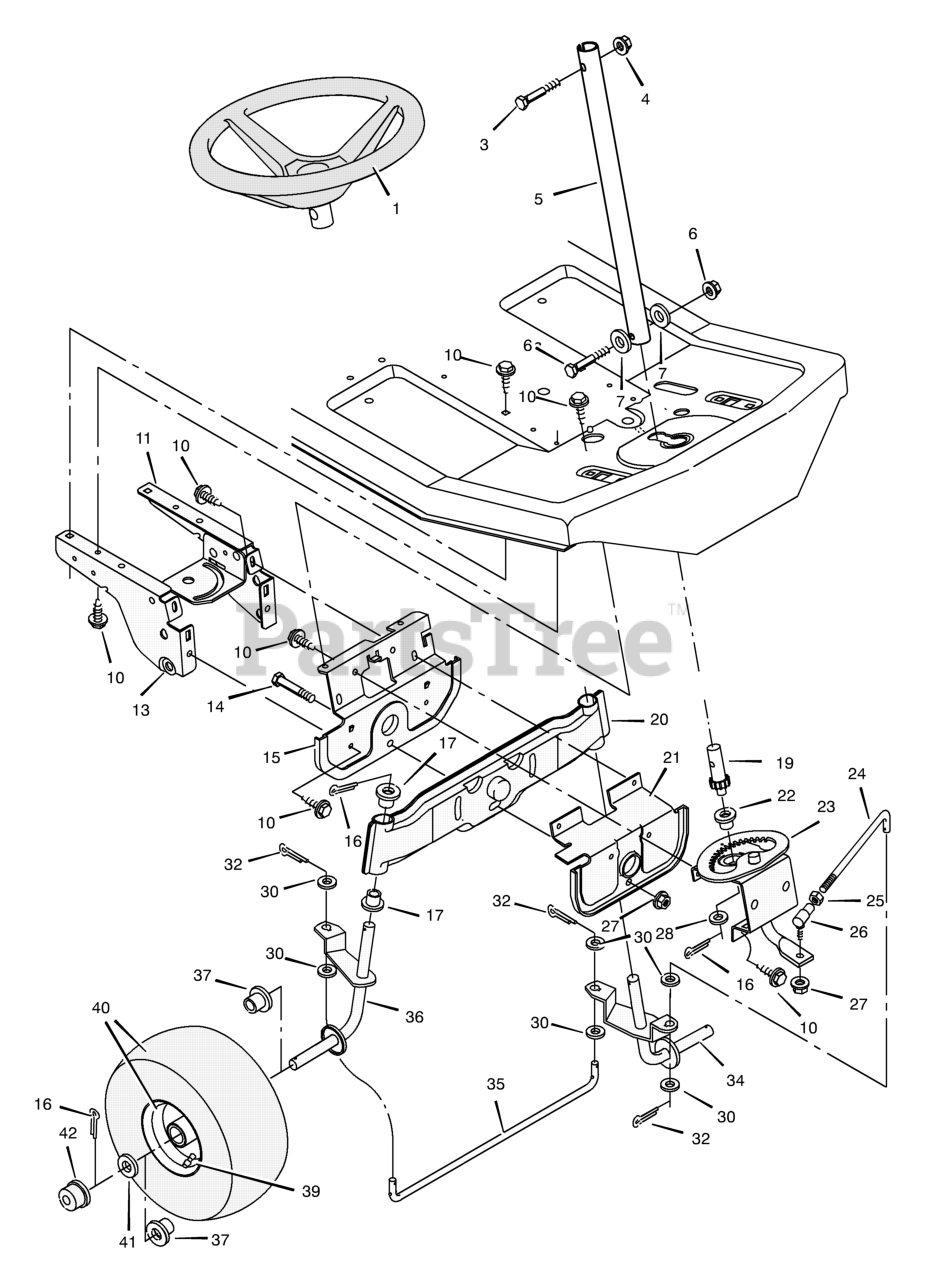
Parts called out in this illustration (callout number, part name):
1	Steering Wheel
3	Bolt, Hex
4	Locknut, Flange
5	Post, Steering
6	Nut, Hex
7	Washer
11	Plate, Left Suspension
13	Plate, Right Suspension
14	Bolt, Hex
15	Support, Front Axle
16	Pin, Cotter
17	Bearing, Spindle
19	Gear, Pinion
20	Axle Assembly, Front
21	Hanger Assembly, Front Axle
22	Bearing
23	Sector Assembly
24	Rod, Drag Link
25	Ball Joint, Steering
26	Nut, Hex
27	Locknut, Flange
28	Washer
30	Washer
32	Pin, Cotter
34	Spindle Assembly, Left
35	Rod, Tie
36	Spindle Assembly, Right
37	Bearing, Wheel
39	Valve Stem
40	Wheel & Tire Assembly
42	Cap, Hub
